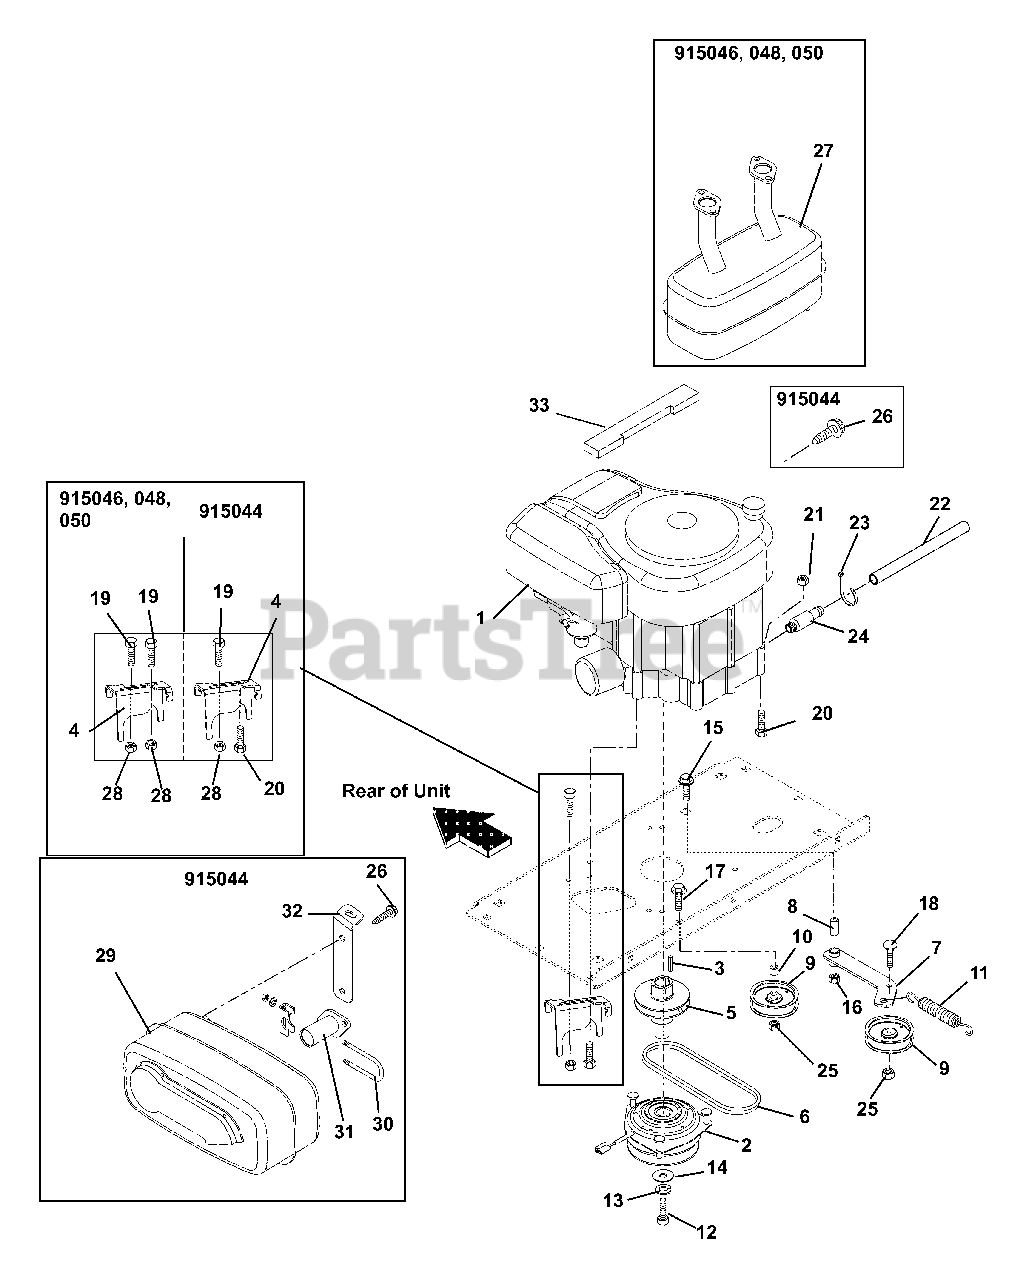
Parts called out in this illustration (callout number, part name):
1	ENGINE, KOHLER COURAGE
2	CLUTCH, ELECTRIC
3	KEY-SQ .25 X 1.50 X .25 SAE
4	STOP, CLUTCH
5	EXTENSION SHAFT
6	BELT,HA WRAPPED
7	WMT, IDLER
8	BSHG-SLV .500X.750X1.560
9	IDLER-FLAT 4.00 X .38 NWHAMSHR
10	BSHG,SPCR .41 X .75 X .88 PM
11	SPRING, EXT
12	BLT-HEX .44-20X4.50 GR8 YWZC
13	@WSHR-LK .44X.109 REG YWZC
14	WSHR-FL-STL .469X2.00X.25 YWZC
15	@BLT-HEX .50-13X2.50 GR5 YWZC
16	@NUT-LK-TOP-FLG .50-13 YWZC
17	@BLT-RDHDSQNK .38-16X2.00 G5YZ
18	@BLT-RDHDSQNK .38-16X1.25 G5YZ
19	@BLT-HEX .38-16X1.00 GR5 YWZC
20	@BLT-HEX .31-18X1.75 GR5 YWZC
21	@NUT-LK-NYL-FLG .31-18 YWZC
22	TUBE, OIL DRAIN
23	CABLE TIE LG 5-1/2
24	VALVE, OIL DRAIN
25	@NUT-LK-CTR-JAM .375-16 YWZC
26	@SCR-TAP .25-20X.50 HWH TR YWZ
27	MUFFLER
28	@NUT-LK-NYL-FLG .38-16 YWZC
29	MUFFLER, KOHLER COURAGE SINGLE
30	MUFFLER CLAMP
31	WMT, MANIFOLD
32	MUFFLER BRACKET
33	FOAM SEAL, 1.5"X3.5"X24"
